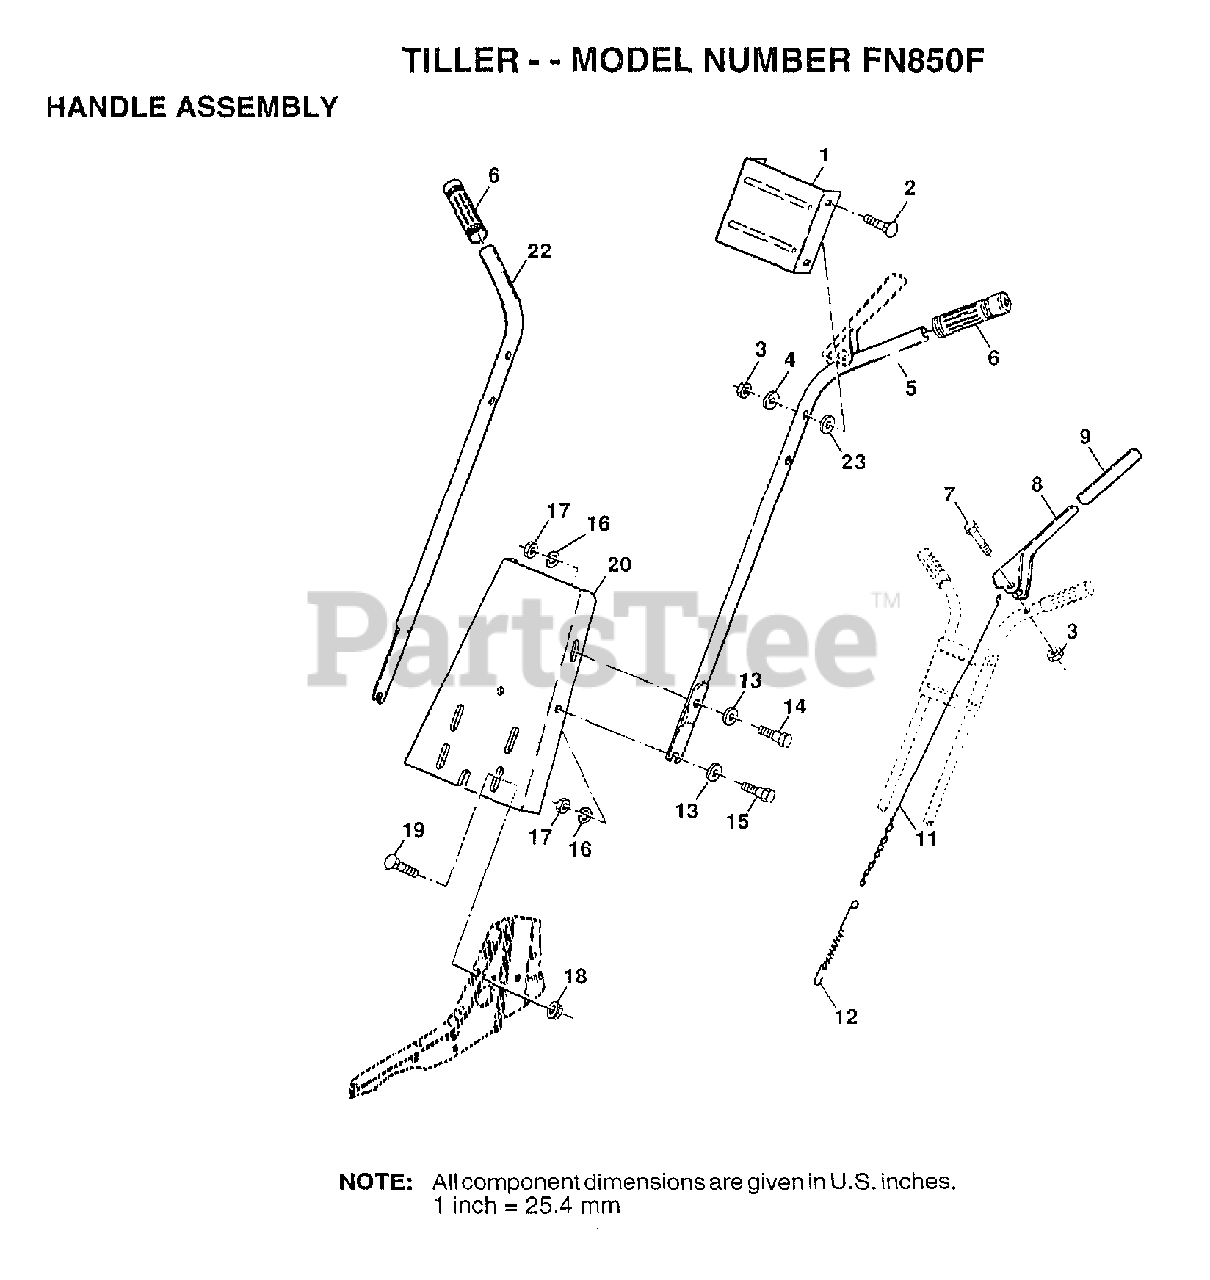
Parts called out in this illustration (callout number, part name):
1	HANDLE BRKT
2	BOLT
4	WASHER
5	HANDLE LH
7	BOLT.HEX.5/16-1.5
9	GRIP T
12	SPRING EXT TI
13	WASHER
15	BOLT
16	LOCKWASHER
17	NUT.HEX.5/16-18
18	NUT
19	BOLT
20	PANEL. HANDLE
22	HANDLE RH
23	WASHER
